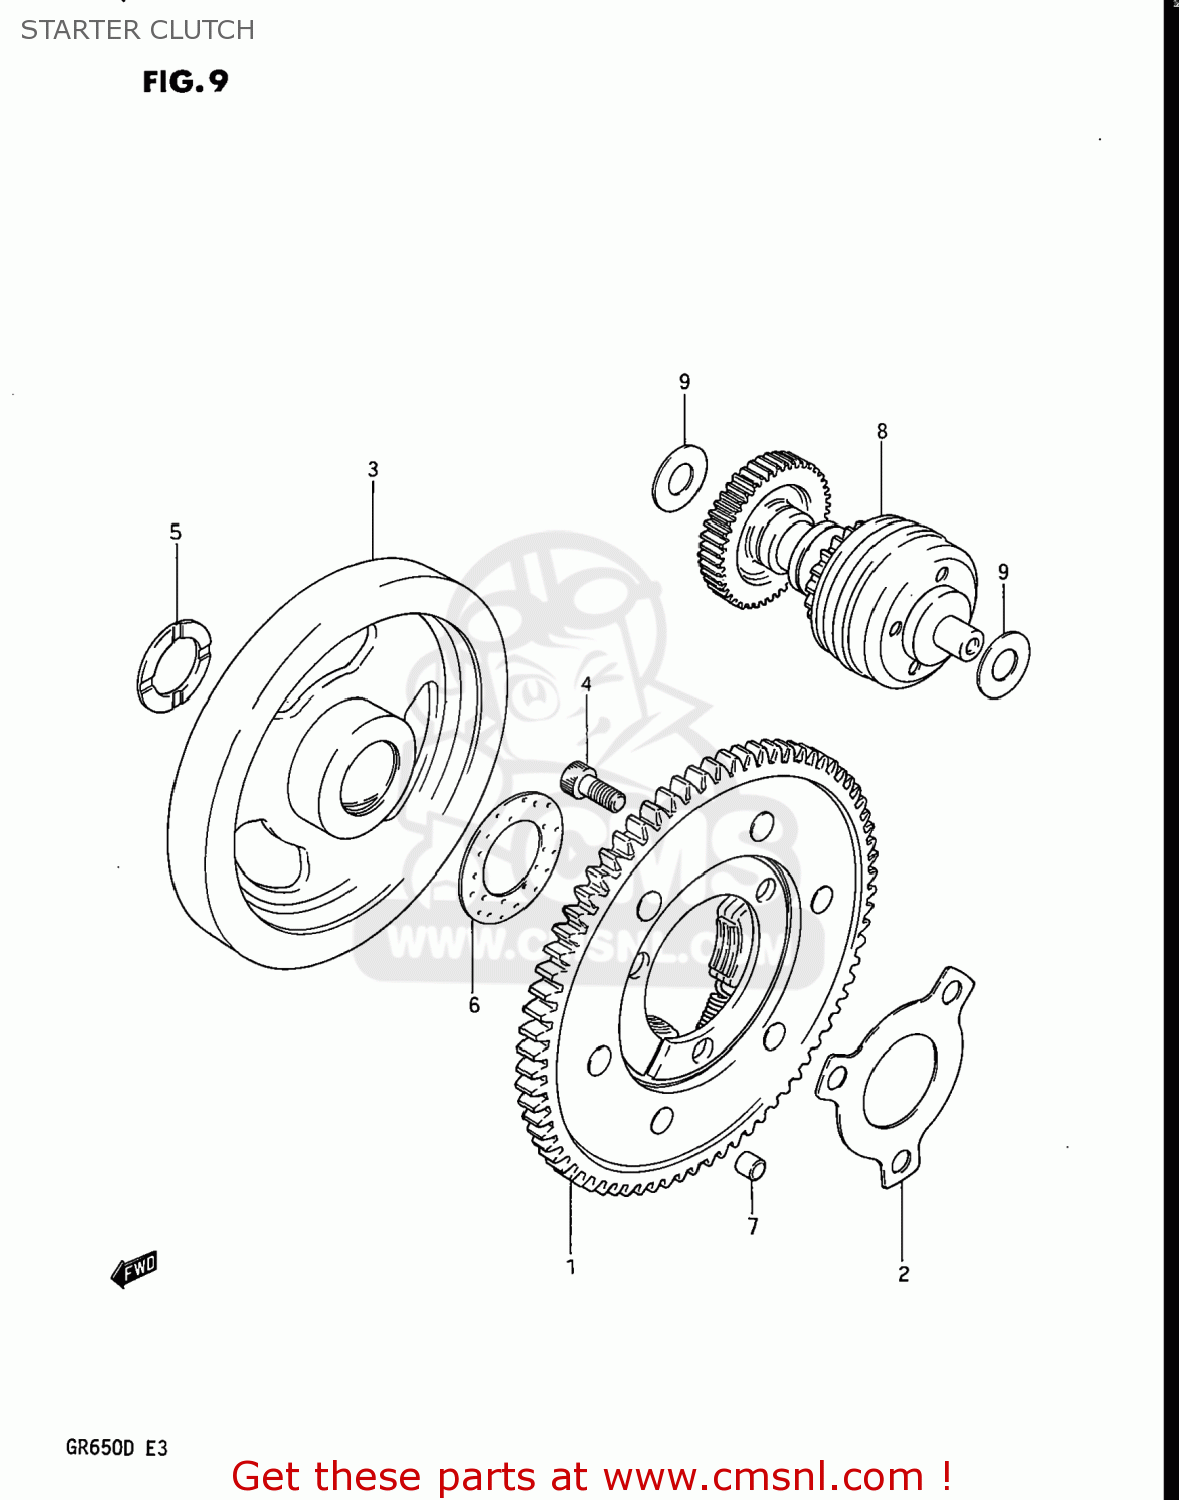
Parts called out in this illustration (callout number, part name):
1	GEAR,STARTER
2	SHIM
3	FLYWHEEL,CLUTCH
4	BOLT
5	WASHER(27X40X2.5)
6	WASHER (27X48X1)
7	PIN(6X8.8)
8	PINION GEAR ASSEMBLY,STARTER
9	SHIM
